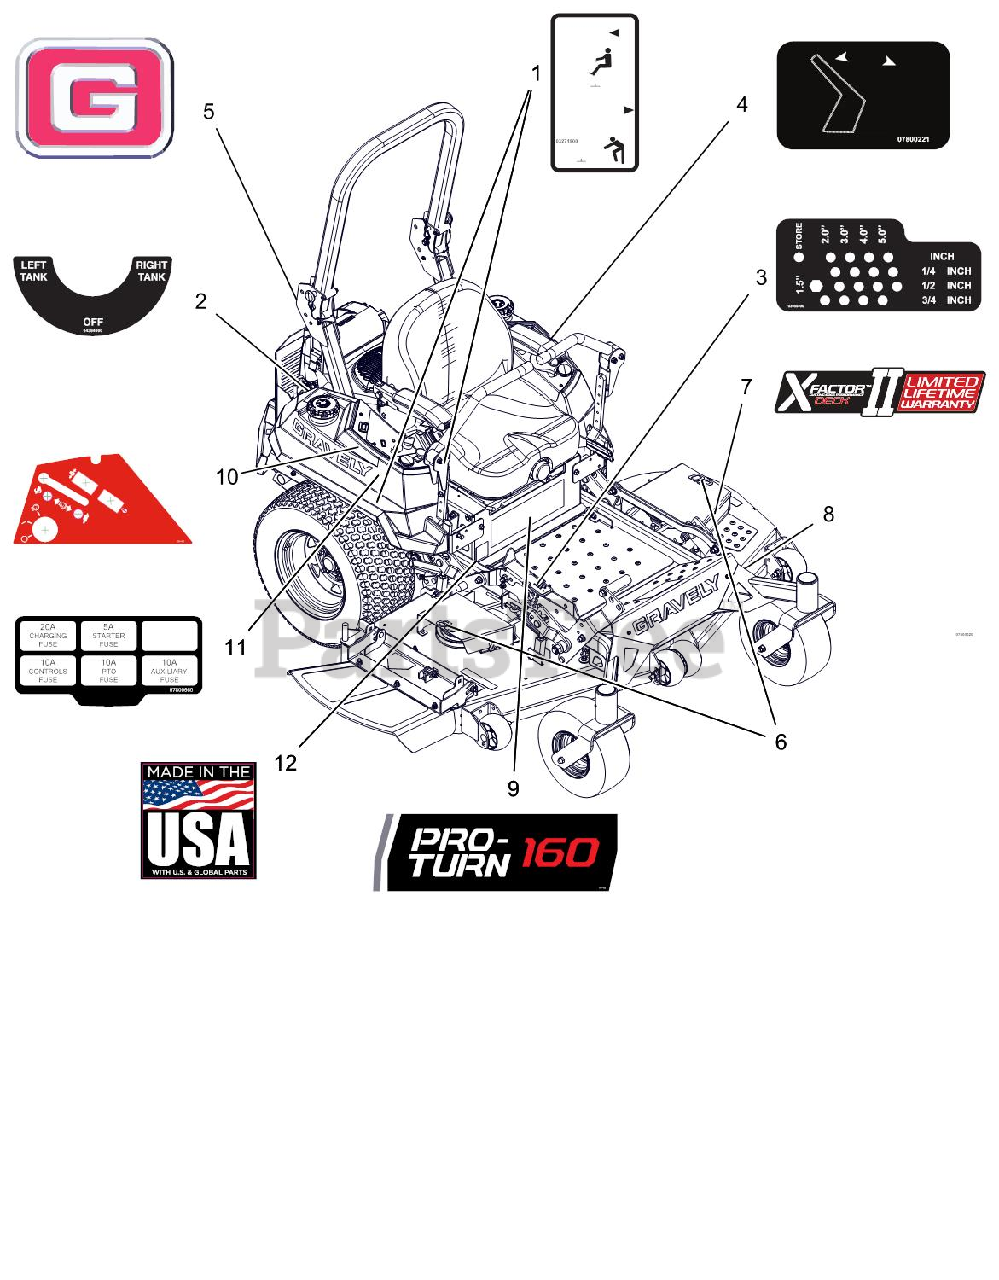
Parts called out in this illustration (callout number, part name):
1	DECAL, TRANSMISSION DISCONNECT
2	DECAL, FUEL VALVE
3	DECAL, HEIGHT OF CUT
4	DECAL - SEAT RELEASE
5	DECAL, GRAVELY BRAND
6	DECAL, 60"
7	DECAL, X-FACTOR DECK
8	DCL,BELT ROUTE-RH BK-SIDE IDLR
9	DECAL, PRO-TURN 160
10	DECAL, EFI CONTROL PANEL
11	DECAL, FUSE BLOCK
12	DECAL, MADE IN USA
